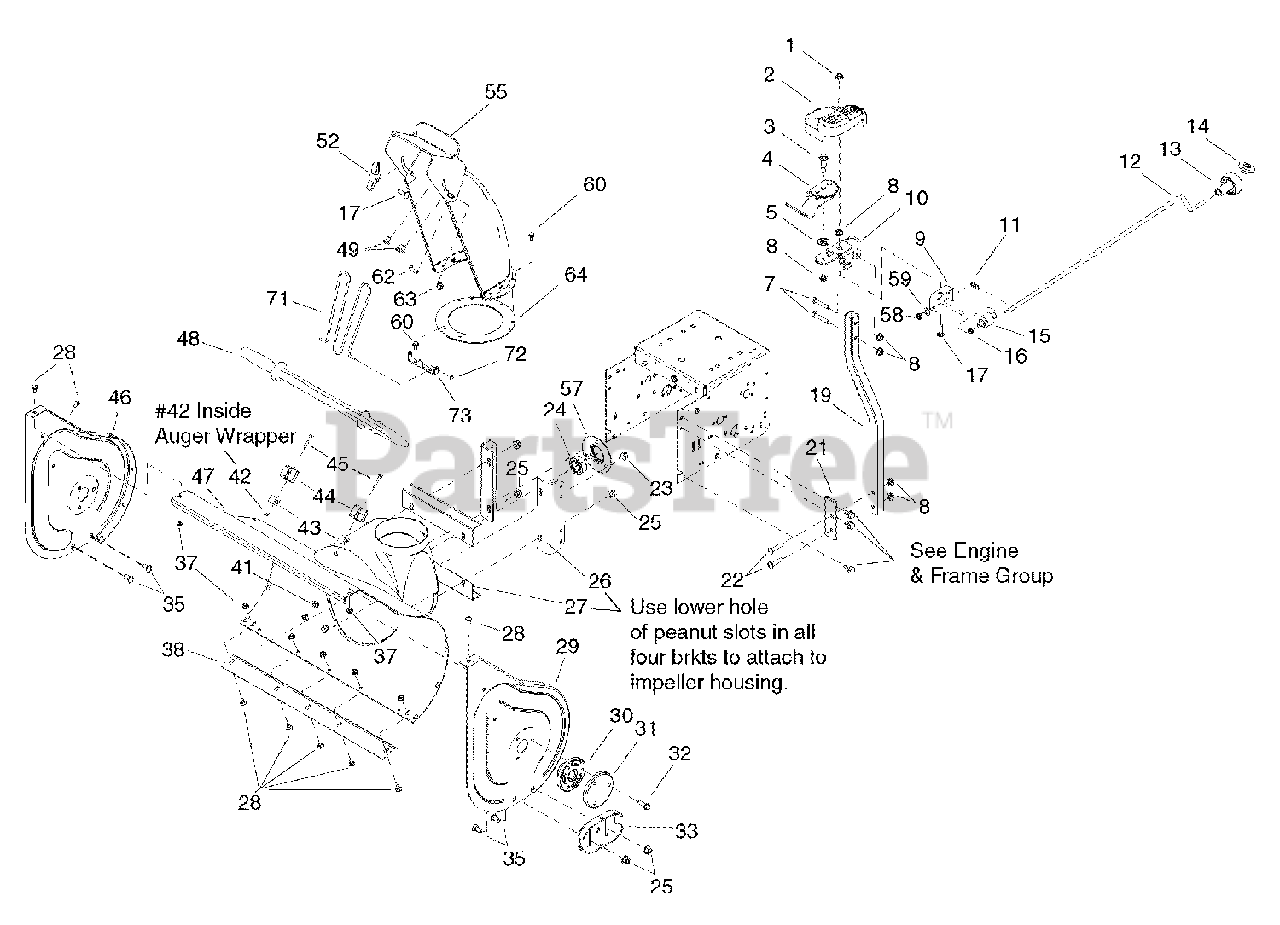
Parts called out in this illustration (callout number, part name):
1	NUT, Hex Flange 5/16-18 Two Way Lock
2	COVER, Gears
3	BOLT, Shoulder 5/16-18 G5
4	GEAR & SUPPORT ASSEMBLY, Chute
5	WASHER, Powdered Metal
7	CAPSCREW, Hex Head 5/16-18 x 1-3/4 G51695314
8	NUT, Hex Keps Conical Washer, 5/16-18
9	SUPPORT, Worm "U" 10GA
10	SUPPORT, Gear & Chute 10GA
11	PIN, Hair Chute Gear
12	ROD, Chute Control E-Coat
13	KNOB, Spinner
14	NUT, Push Pal 3/8 Diameter Stud Capped
15	WORM, Chute L.H.
16	BUSHING
17	BOLT, Carriage, Short Neck, 5/16-18 x 1
19	TUBE, Offset Intermediate
21	SUPPORT, Tube 10GA
22	CARRIAGE BOLT, 5/16-18 x 1-1/2 G5
23	SCREW, Hex Whiz Lock Flange 5/16-18 x 1/2
24	BEARING, Ball
25	NUT, Hex Flange 3/8-16 ESNA
26	BRACKET, Housing 12GA
27	ANGLE, Fill Strip
28	CARRIAGE BOLT, 1/4-20 x 1/2 G5
29	PLATE, End L.H.
30	HOUSING, Auger Bearing
31	CAP, Bearing
32	SCREW, Hex Washer Head Taptite 5/16-18 x 1
33	SKID, Shoe Reversible
35	CARRIAGE BOLT, 3/8-16 x 3/4 G5
37	NUT, Hex Flange 1/4-20 Whiz Lock Large
38	BLADE, Scraper 24"
41	RETAINER, Nut, 5/16-18
42	NUT, Hex Lock 10-24 w/Nylon Insert
43	BLOCK, Universal Pivot
44	CLIP, Retainer
45	CAPSCREW, Hex Washer, #10 x 1-1/4
46	PLATE, End R.H. 14GA
47	WRAPPER ASSEMBLY, 24" Auger
48	STICK, Cleanout w/Brush
49	SCREW, Phillips Head Taptite, Torx 5/16C x 1/2
52	WINGNUT, 5/16-18
55	CHUTE & DEFLECTOR ASSEMBLY
57	RETAINER, Bearing
58	NUT, Hex Lock Jam ESNA Lite 3/8-24
59	WASHER, Cup
60	SCREW, Hex Washer Head Taptite 1/4-20 x 1/2
62	SCREW, Truss Head Torx 5/16-18 x 3/4
63	NUT, Hex Flange 5/16-18 ESNA
64	RING, Chute Base
71	GUARD, Chute
72	NUT, Push
73	BRACKET, Chute Guard 12GA
